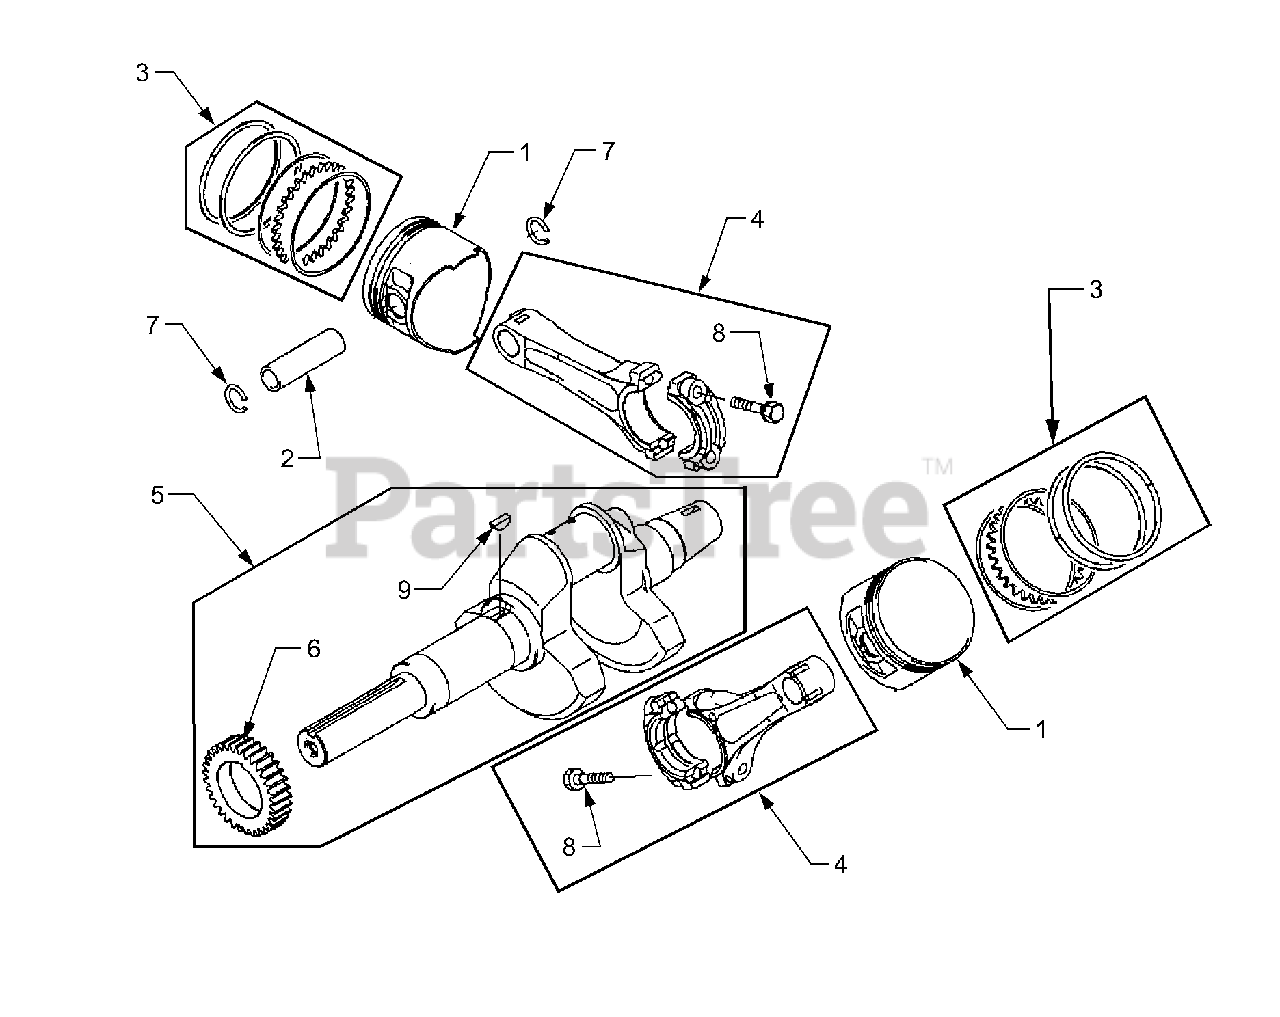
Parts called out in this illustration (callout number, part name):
3	Ring Set, Piston
4	Rod, Connecting
5	Crankshaft Assembly
6	Gear, Spur, 33T
9	Key, Woodruff
